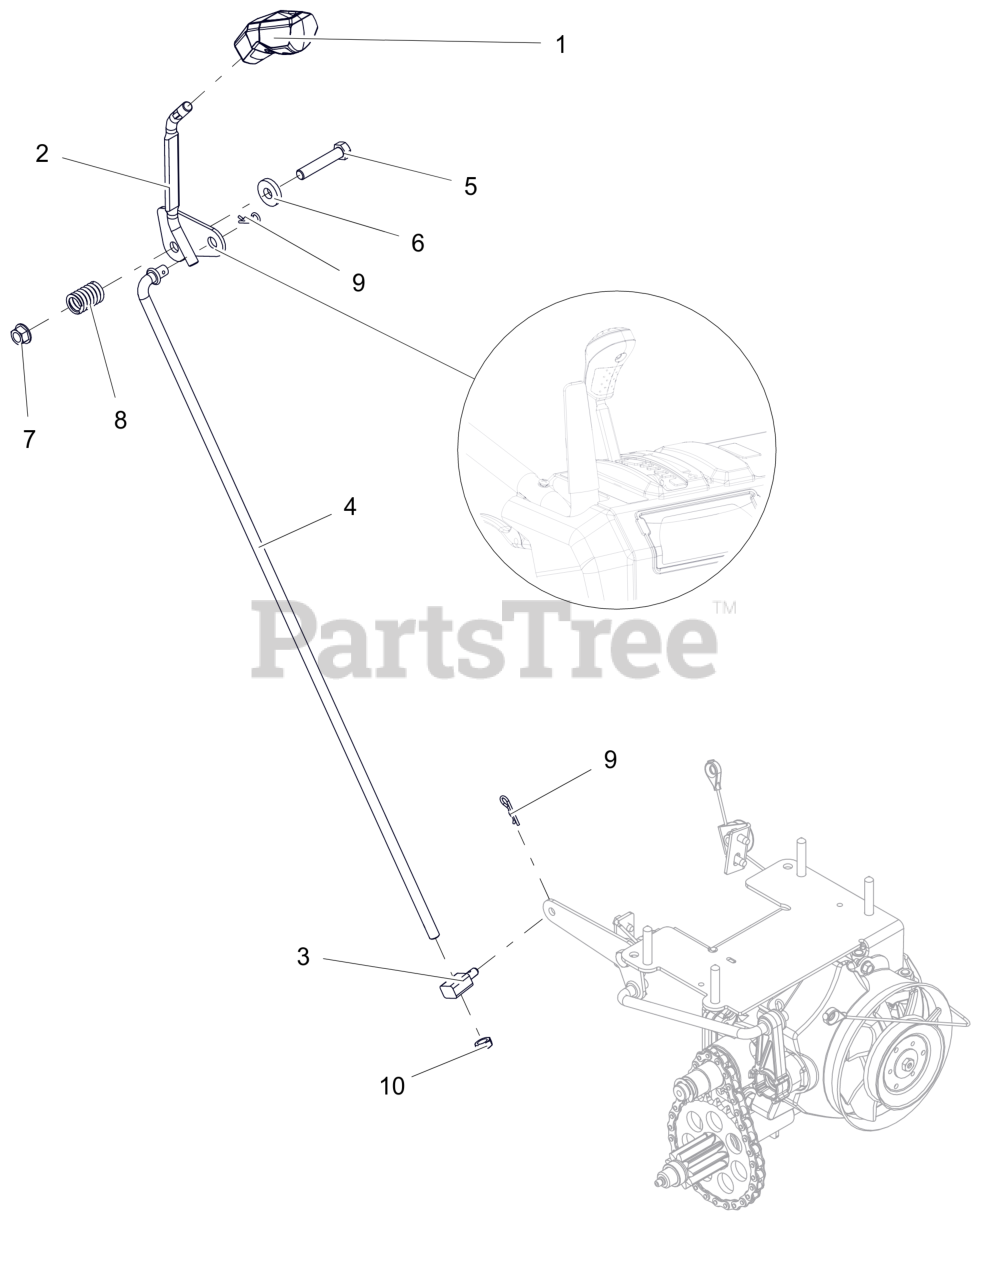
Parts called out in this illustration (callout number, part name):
1	KNOB, CONTROL
2	WELDMENT,LG DASH SPEED CONTROL
3	PIVOT,SHIFT ROD .375-16(TRUNN)
4	ROD, SHIFT - PRO
5	BLT,HEX .38-16X2.00 G5 ZCC
6	WSHR, FLT .406X1.00X.188 ZCC
7	NUT-LK-TOP-FLG .38-16 ZC120
8	SG-COMP .125X.781X1.250
9	PIN, HAIR #213 .08X1.19 ZCC
10	NUT-JAM .375-16 G2 ZCC
